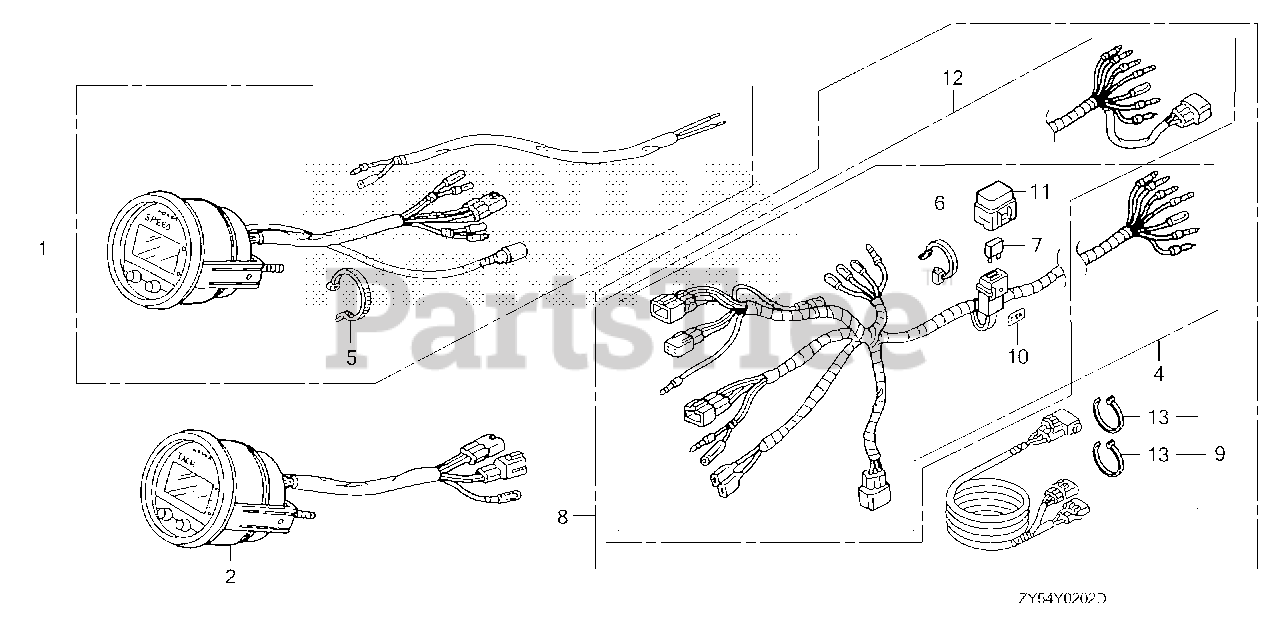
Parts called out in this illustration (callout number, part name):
1	SPEEDOMETER KIT (DIGITAL) (FOR 32540-ZY3-800/801)
2	METER KIT, TACHO (DIGITAL) (USA)(USE FOR 32540-ZY3-801) (NOT AVAILABLE)
4	HARNESS ASSY., METER (A)(DIGITAL)
5	BAND (BLACK 3.5X140)
6	TIE, CABLE
7	FUSE, BLADE (7.5A)
8	HARNESS KIT, METER (DIGITAL) (INCLUDE 32540-ZY3-801)
9	WIRE ASSY., INDICATOR (DIGITAL)
10	MARK, FUSE (7.5A)
11	COVER ASSY., FUSE (7.5A)
13	TIE, CABLE (2.4X92) (NATURAL)
